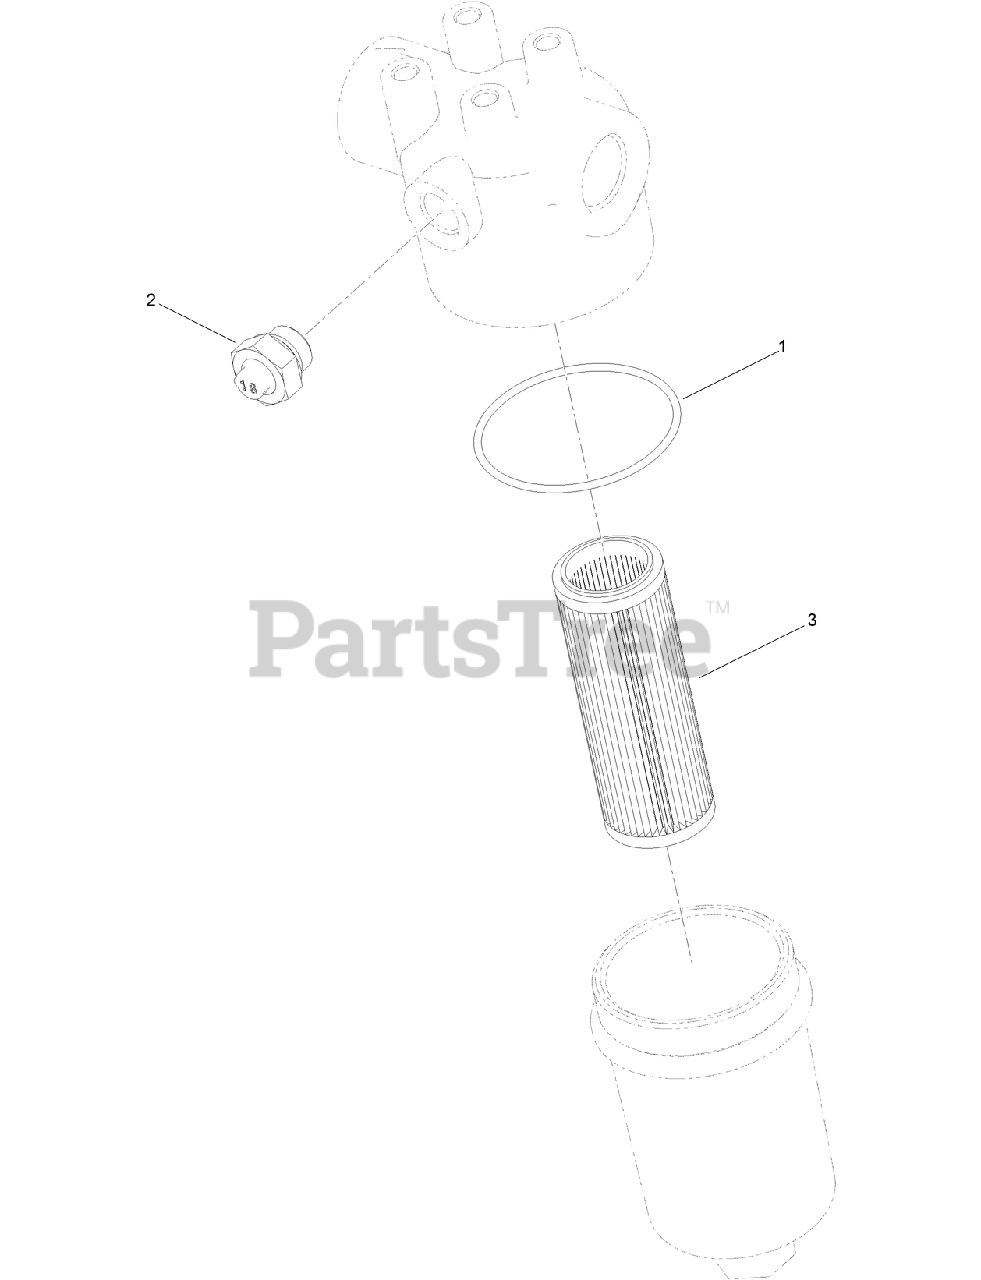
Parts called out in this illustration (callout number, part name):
1	O-RING
2	INDICATOR-FILTER, OIL
3	ELEMENT-FILTER, 6 MICRON ABS
